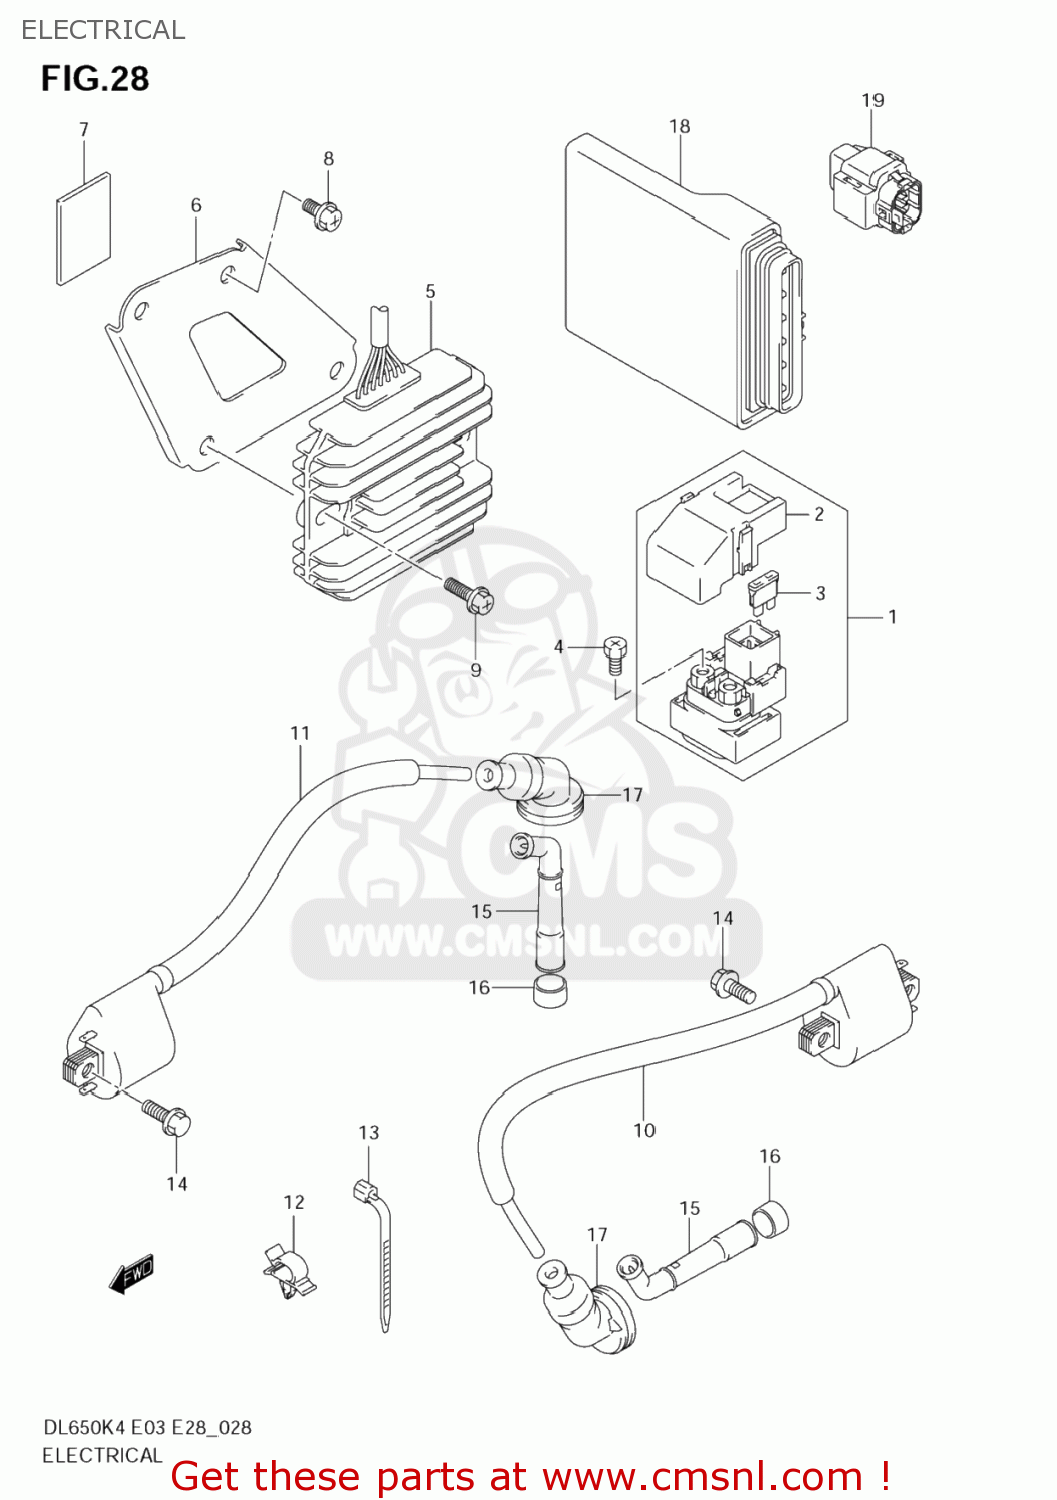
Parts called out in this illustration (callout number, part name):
1	RELAY ASSY,STARTING MOTOR
2	COVER
3	FUSE(30A)
4	SCREW(6X8)
5	RECTIFIER ASSY
6	BRACKET,RECT FTG
7	PROTECTOR(170X95X3.0)
8	BOLT
9	BOLT
10	COIL ASSY,IGNITION
11	COIL ASSY,IGNITION
12	CLAMP
13	CLAMP(L:165)
14	SCREW
15	CAP ASSY,SPARK PLUG
16	SEAL,SPARK PLUG CAP
17	SEAL,HIGH TENS
18	CONTROL UNIT,FI
19	SENSOR ASSY,FUEL CUT
